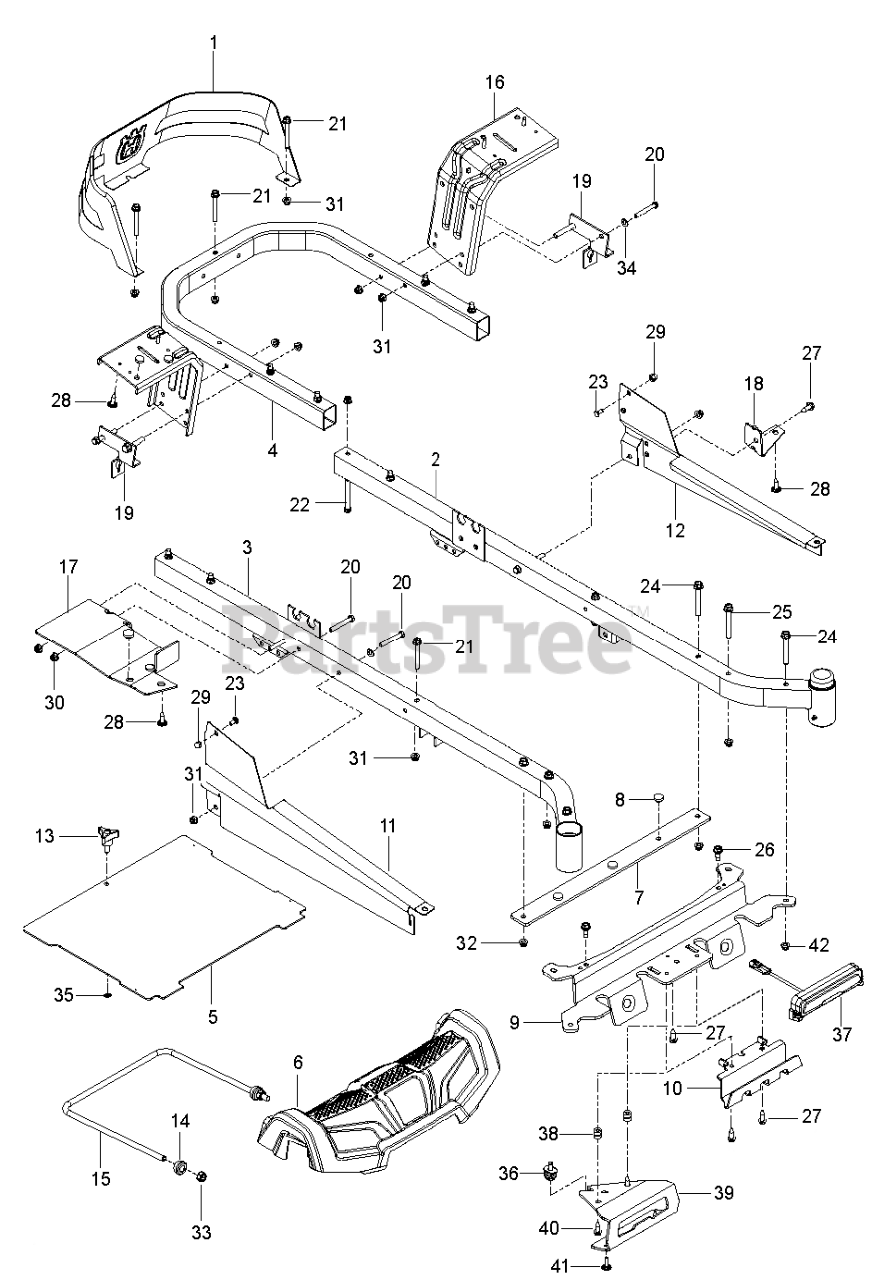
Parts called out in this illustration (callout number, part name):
1	GUARD.ENGINE.HUSQ.RZ.X498
2	FRAME.TUBE.RZ.MAIN.WELD.LH.ORG
2	FRAME.TUBE.RZ.MAIN.WELD.RH.ORG
3	FRAME.TUBE.RZ.MAIN.WELD.RH.ORG
3	FRAME.TUBE.RZ.MAIN.WELD.LH.ORG
4	TUBE.PNT.FRAME.RER.HUSQ.23".RZ
5	PLATES
5	PLATE, FOOT W/DECALS RZ
5	PLATE RZ FOOTREST HUSQVARNA OR
6	FRONT COVER RZ REFRESH
7	FOOTREST.PLATE.SUPPORT.X431
7	SUPPORT.RZ.FOOTREST.PLATE.X43
8	GROMMET.BUMPER
9	CROSS.PNT.MEMBER.BLK
10	SKID.PLATE.PNT.RZ.REF.SIVER
10	SKID PLATE RZ REFRESH STANDARD
11	COVER.RAIL.RH.RZ.X668
11	COVER.RAIL.LH.RZ.X668
12	COVER.RAIL.RH.RZ.X668
12	COVER.RAIL.LH.RZ.X668
13	KNOB W/STUD
14	BUSHING SPHERICAL SUSP. FRONT
15	LINK, FRONT SUSP.
16	FENDER.SUPPORT.PNT.X431
17	SUPPORT.PNT.RH.CONSOLE.FRONT
17	SUPPORT RZ REFRESH RH CONSOLE
18	SUPPORT RZ REFERSH LH CONSOLE
18	SUPPORT.PNT.LH.CONSOLE.FRONT
19	BRKT ROD.BYPASS.EZT.X431
20	BOLT.FIN HEX 5/16-18UNC X2 1/4
21	BOLT HEX 5/16-18 GR 5
21	BOLT HEX
22	BOLT.HEX.FIN.3/8-16 X 3.GR5
23	BOLT.CARRIAGE.5/16-18.7/16
24	HHFS 3/8-16 X 3 GRD 5 ZD
25	BOLT SHOULDER,FLANGED,3/8-16X3
26	BOLT.5/16-18.THRD.ROLL.SHOULDR
27	BOLT.FIN HEX 5/16-18UNC X2 1/4
27	BOLT.5/16HEX.WHS.HD
28	SCREW.#10 X 0.750.BOS
29	NUT ACORN,FLANGED,5/16-18
30	NUT LOCK HEX FLANGE 5/16-18
31	5/16-18 NYLOC FLANGE NUT
32	NUT 3/8-16 HEX FLG NYLOC ZD
33	7/16-14 HEX NUT W/NYL RING ZD
34	WASHER
35	WASHER 5/16"
36	SCREW.ADJ.ISOLATOR.BOLT.ASSY
37	LIGHT.ZTR.LED.ASM
38	GROMMET.RUBBER.PUSHIN
39	BRACKET.SKIDPLTE.LED.RFRSHX417
40	BOLT.5/16-18X1.25
40	BOLT.5/16-18.THRD.ROLL.SHOULDR
41	SCREW.#10 X 0.500
42	NUT 3/8-16 HEX FLG NYLOC ZD
